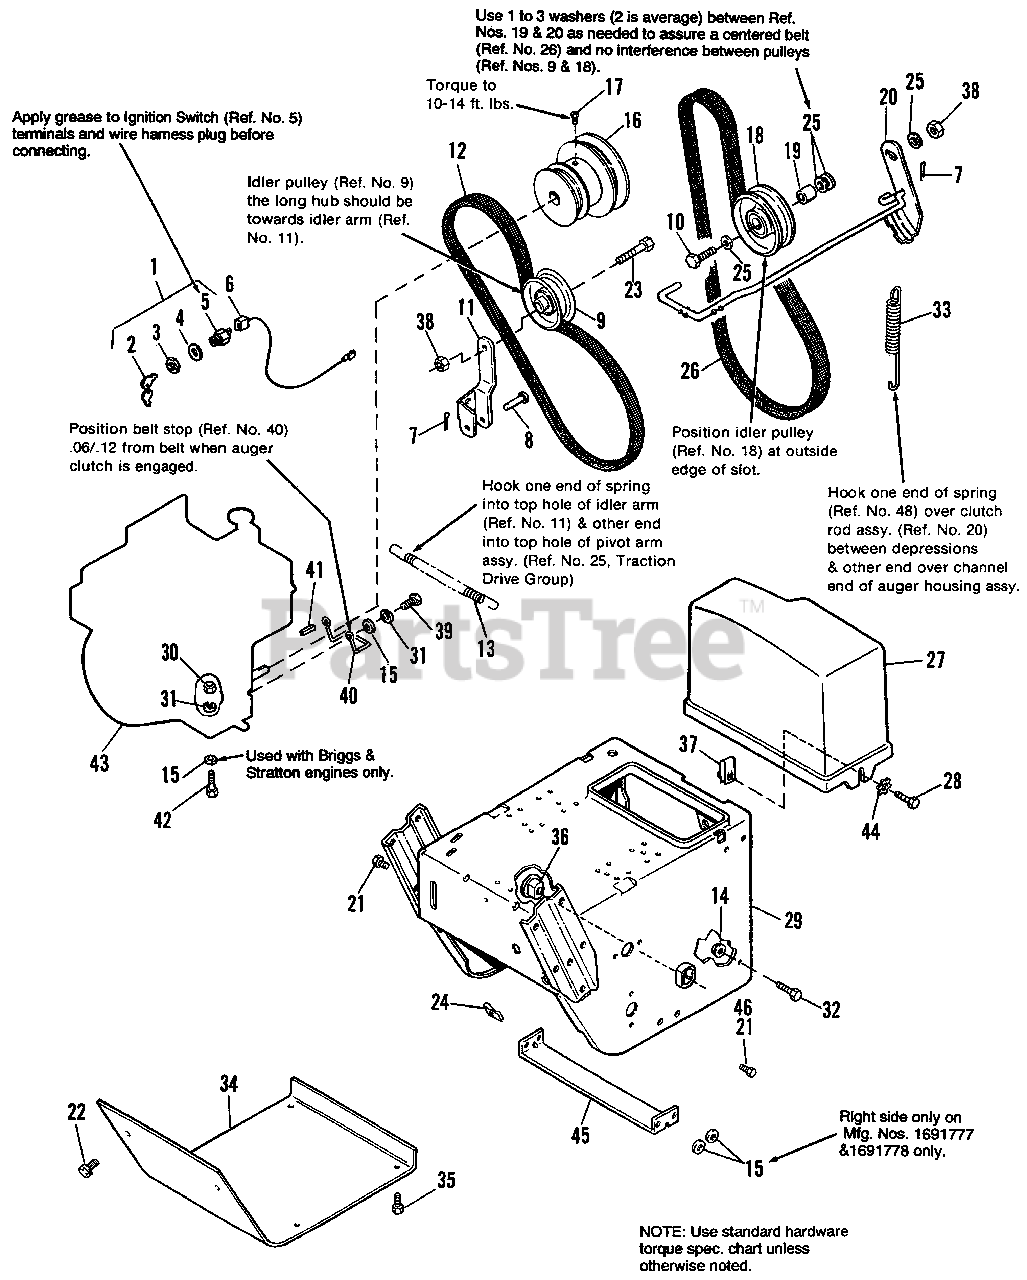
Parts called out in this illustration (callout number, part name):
1	SWITCH, Key (Inc. Ref. Nos. 2, 3, 4 & 5) (Electric Start only)
2	KEYS (Electric Start only)
3	NUT, Hex, 5/8-32 (Electric Start only)
4	LOCKWASHER Int. 5/8 (Electric Start only)
5	SWITCH (See Ref No.1) (Electric Start only)
6	WIRE, Ground (Electric Start only)
7	PIN, Cotter, 1/8 x 3/4
8	PIN
9	PULLEY, Idler
10	CAPSCREW, Hex Hd., 3/8-16 x 1-3/4
11	ARM, Idler, Traction
12	BELT, Traction (Electric Start only)
12	BELT, Traction (Manual Start only)
13	SPRING, Idler
14	NUT, Hex, Whizlock
15	WASHER, Flat, 11/32 (Qty. 6 On Electric Start)
16	PULLEY, Engine (Electric Start only)
16	PULLEY, Engine (Manual Start only)
17	SETSCREW, Socket Hd., 5/16-18 x 5/8
18	PULLEY ASSY.
20	CLUTCH ROD & BRAKE ASSY.
21	SCREW, Taptite, 5/16-18 x 3/8
22	SCREW, Taptite, 1/4-20 x 5/8
23	CAPSCREW, Hex Hd., 3/8-16 x 1-3/4 (1691900 & 1691946)
24	NUT, Speed, 1/4-20
25	WASHER, Flat, 13/32
26	BELT, Auger Drive (Electric Start only)
26	BELT, Auger Drive (Manual Start only)
27	GUARD, Belt
28	SCREW, Truss Hd., 5/16-18 x 3/4
29	FRAME, Main
30	NUT, Hex, 5/16-18
31	LOCKWASHER
32	CAPSCREW, Whizlock 5/16-18 x 3/4
33	SPRING, Brake
34	COVER, Bottom
35	SCREW, Tapttite, 1/4-20 x 3/8
36	BUSHING, Axle
37	NUT, Pal, 5/16-18
38	LOCKNUT, Jam, 3/8-16
39	CAPSCREW, Hex. Hd., 5/16-24 x 3/4
40	BELT STOP (Electric Start only)
40	BELT STOP (Manual Start only)
41	KEY, 3/16 x 3/16 x 1-1/2 (Electric Start only)
41	KEY, 1/4 x 1/4 x 1-1/2 (Manual Start only)
42	CAPSCREW, Hex Hd., 5/16-18 x 1-3/4 (Electric Start only)
42	CAPSCREW, Hex Head 5/16-18 x 2 G5
43	ENGINE, Tecumseh, 8 H.P. Electric Start
43	ENGINE, Briggs & Stratton, 8 H.P. Manual Start
44	LOCKWASHER, Ext. Tooth, 5/16
45	SUPPORT, Tie Bar
46	SCREW, Taptite, 5/16-18 x 3/8 (1691777 & 1691778)
